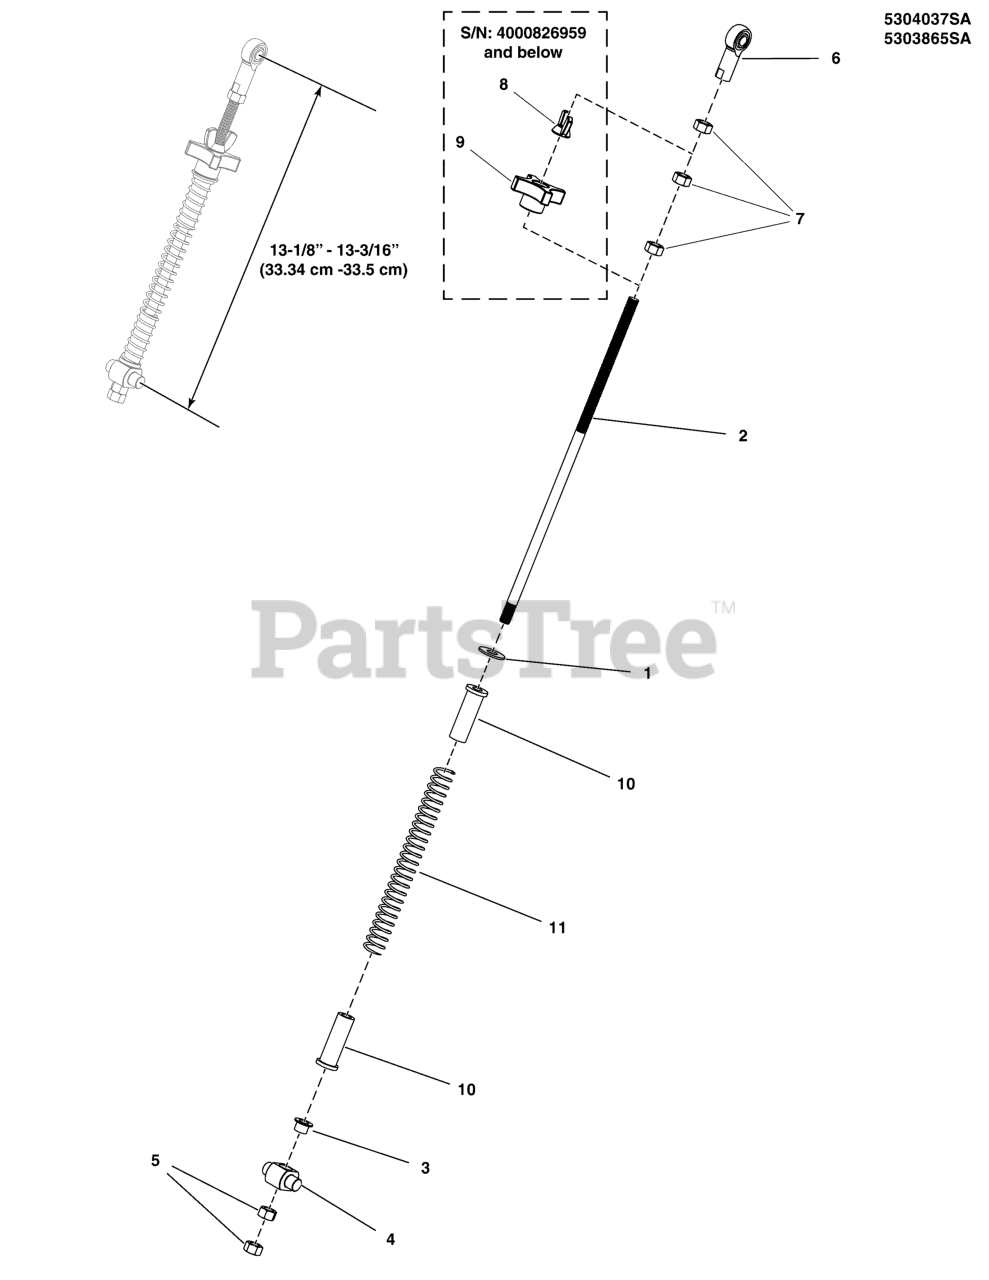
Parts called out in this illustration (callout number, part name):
1	WASHER, 3/8 USS
2	ROD, CONTROL SYSTEM, WALK
3	BUSHING, .38ID X .47 OD X .38L, FL
4	TRUNION, 1/2" POSTS, STAINLESS
5	NUT, 3/8-16 HEX
6	BALL JOINT, 3/8-24 FEMALE
7	NUT, 3/8-24 HEX
8	WING NUT, 3/8-24, CZ
9	KNOB, 4 ARM, 3/8-24
10	FLANGED BUSHING, 3/8IDX.63ODX.8125FL
11	SPRING,COMP,.645IDX8.00LGX.080WR,BLK E-C
